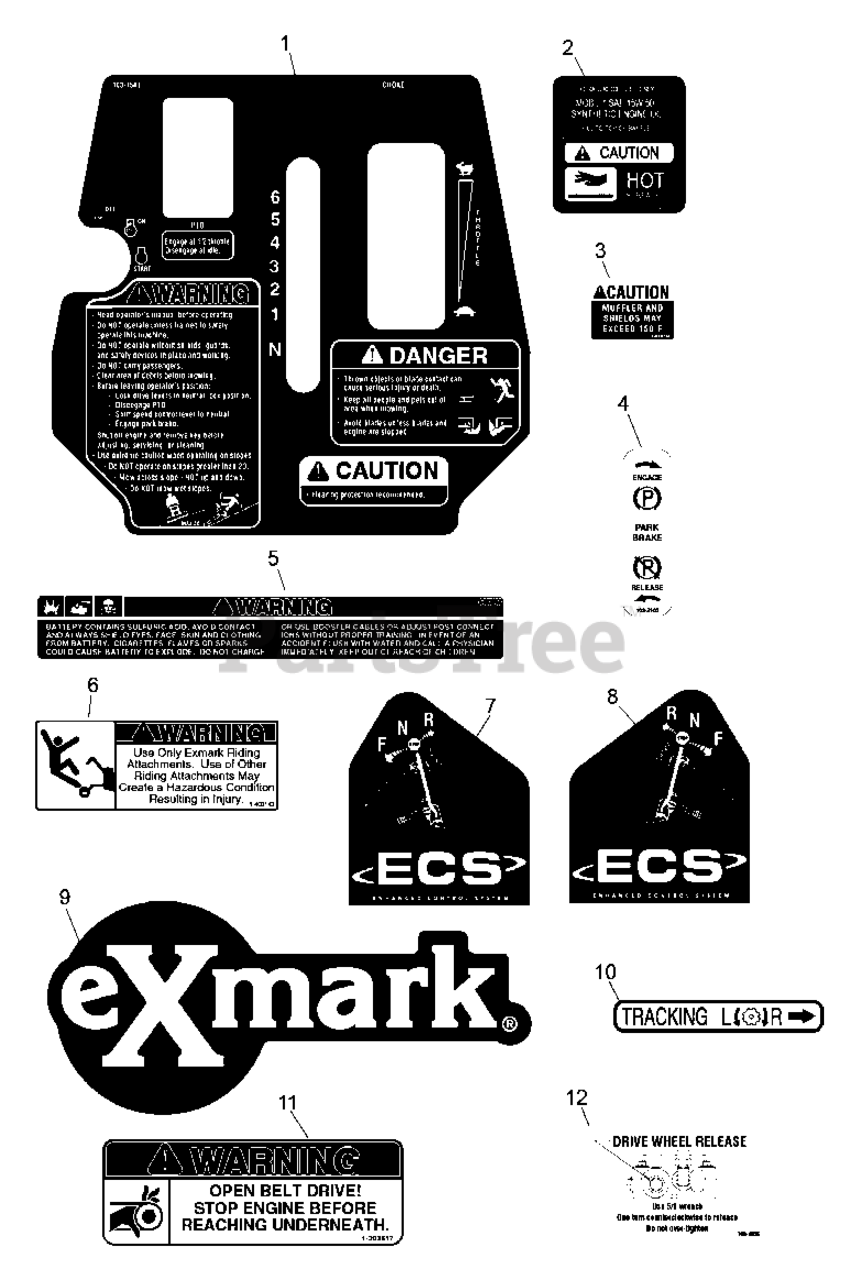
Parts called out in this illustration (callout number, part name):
1	DECAL,TTH ECS CONSOLE
4	DECAL,PARKING BRAKE
5	DECAL-BATTERY
6	DECAL,SULKY WARNING
7	DECAL,LH ECS INSTRUCTION
8	DECAL,RH ECS INSTRUCTION
9	DECAL,EXMARK LOGO
10	DECAL,TRACKING ADJUST
11	DECAL,BELT DRIVE
12	DECAL,DRIVE RELEASE
